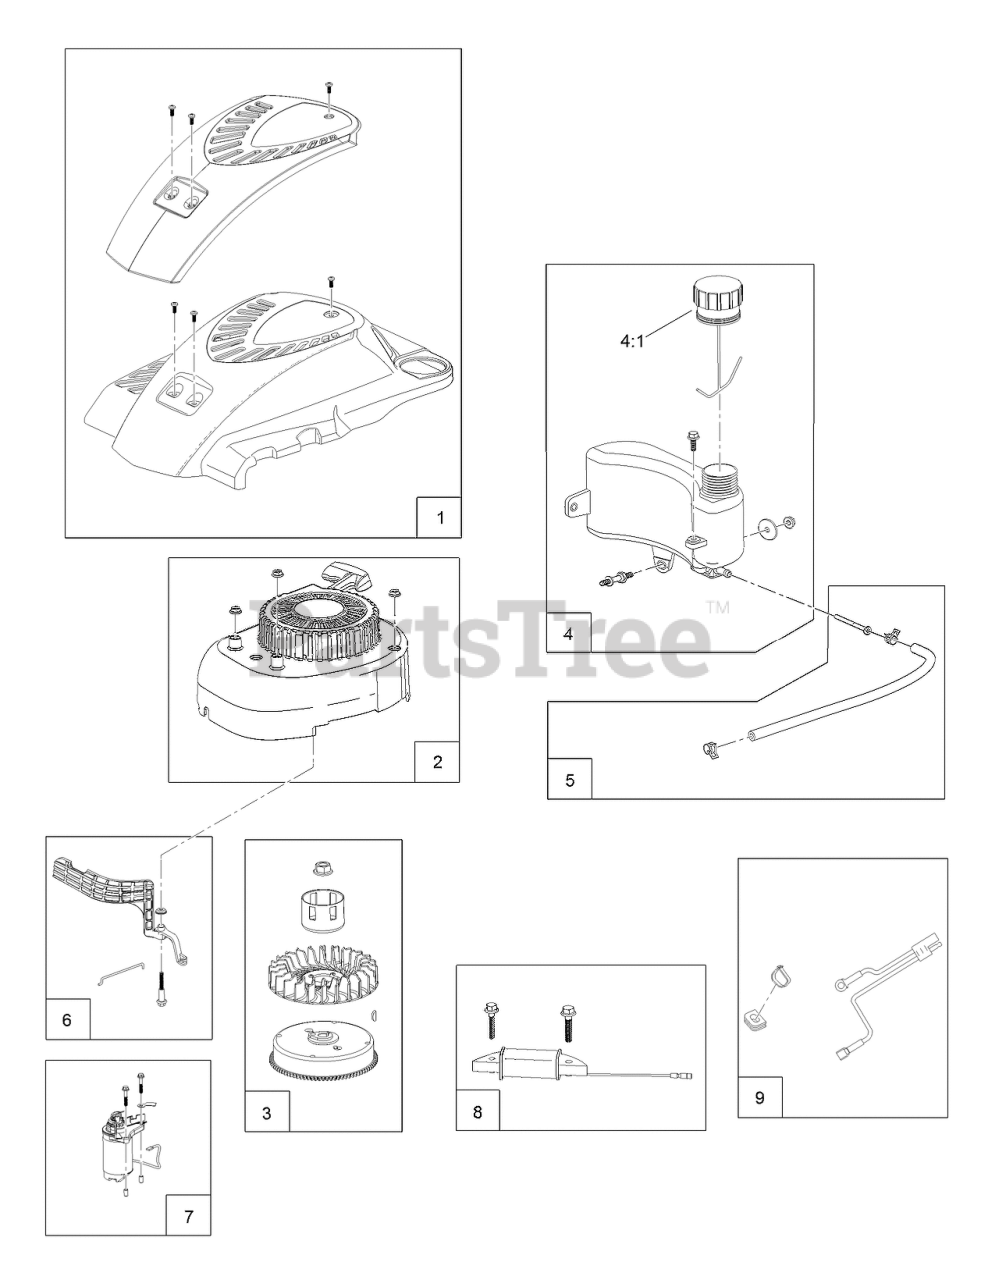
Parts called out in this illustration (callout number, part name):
1	SHROUD ASM
2	RECOIL AND BLOWER SHROUD KIT
3	FLYWHEEL AND FAN KIT
4	FUEL TANK KIT
4:1	CAP-FUEL
5	FUEL LINE KIT
6	AIR VANE KIT
7	STARTER ASM
8	ALTERNATOR ASM
9	WIRE HARNESS KIT
